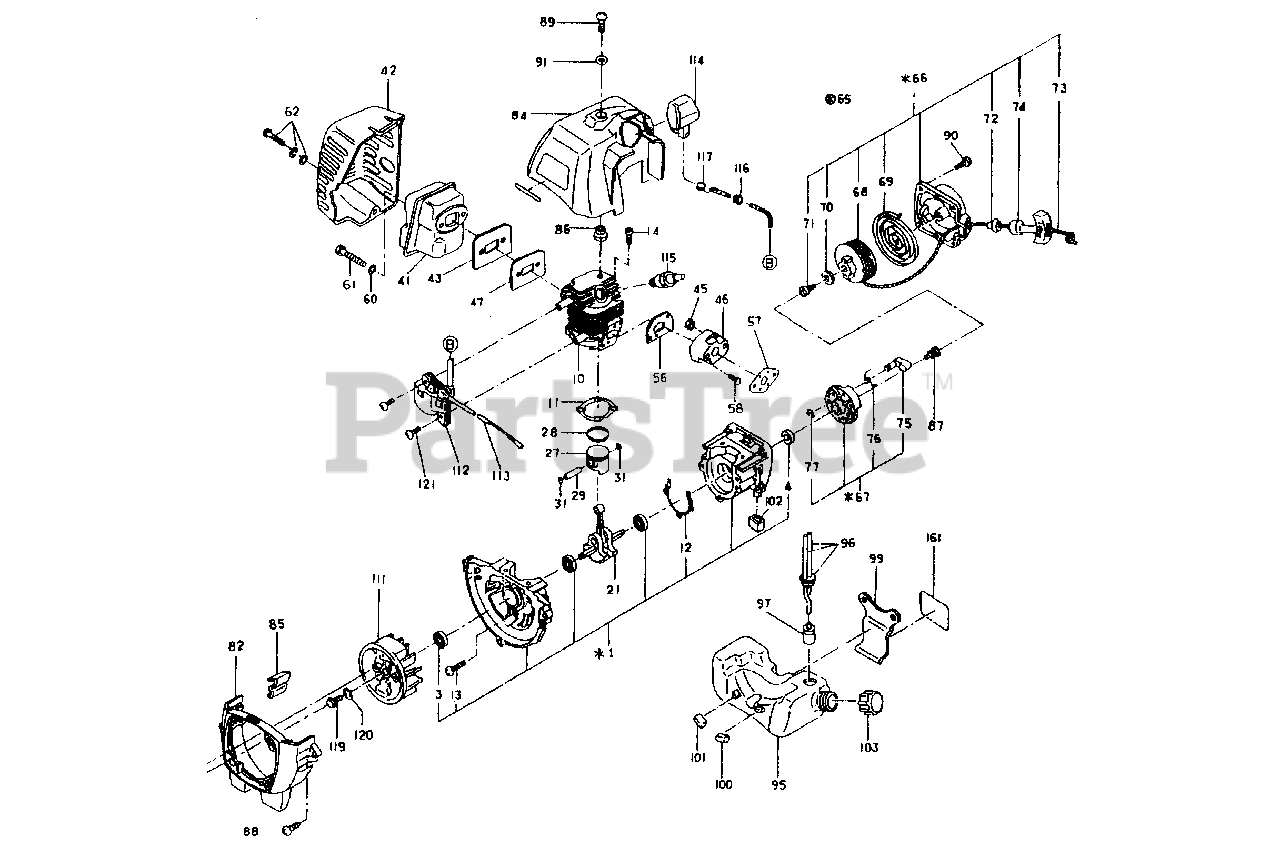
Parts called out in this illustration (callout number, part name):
1	Crankcase, Complete
3	Kit, Oil Seal (Inc. 4)
10	Cylinder
11	Gasket, Cylinder
12	Gasket, Crankcase
14	Socket Head Bolt
21	Crankshaft Complete
28	Ring, Piston
29	Kit, Pin, Piston (Incl. 31)
30	Needle Roller Bearing
41	Muffler, Exhaust
42	Cover, Muffler
43	Gasket, Muffler
46	Insulater
47	Gasket, Muffler
56	Gasket, Insulater
57	Gasket, Air Cleaner
58	Screw Assembly
60	Kit, Washer (Incl. 61)
66	Starter, Rewind (Incl. 68-74)
67	Pulley, Starter (Incl. 75-77)
69	Spiral Spring
72	Rope Guide
73	Starter Rope
74	Starter Knob
75	Ratchet
76	Return Spring
82	Housing, Blower
84	Cover, Cylinder
85	Plate, Baffle
86	Spacer, Cover
87	Bolt Assembly
88	Screw, Pan Head
90	Screw Assembly
95	Tank, Fuel
96	Tube Assembly
99	Plate, Fuel Tank
100	Plate Kit (Incl. 101 - 102
103	Cap, Fuel Tank Ass'y
111	Flywheel
114	Kit, Cap, Plug (Incl. 117)
116	Grommet
119	Kit, Bolt Assembly (Incl. 120)
